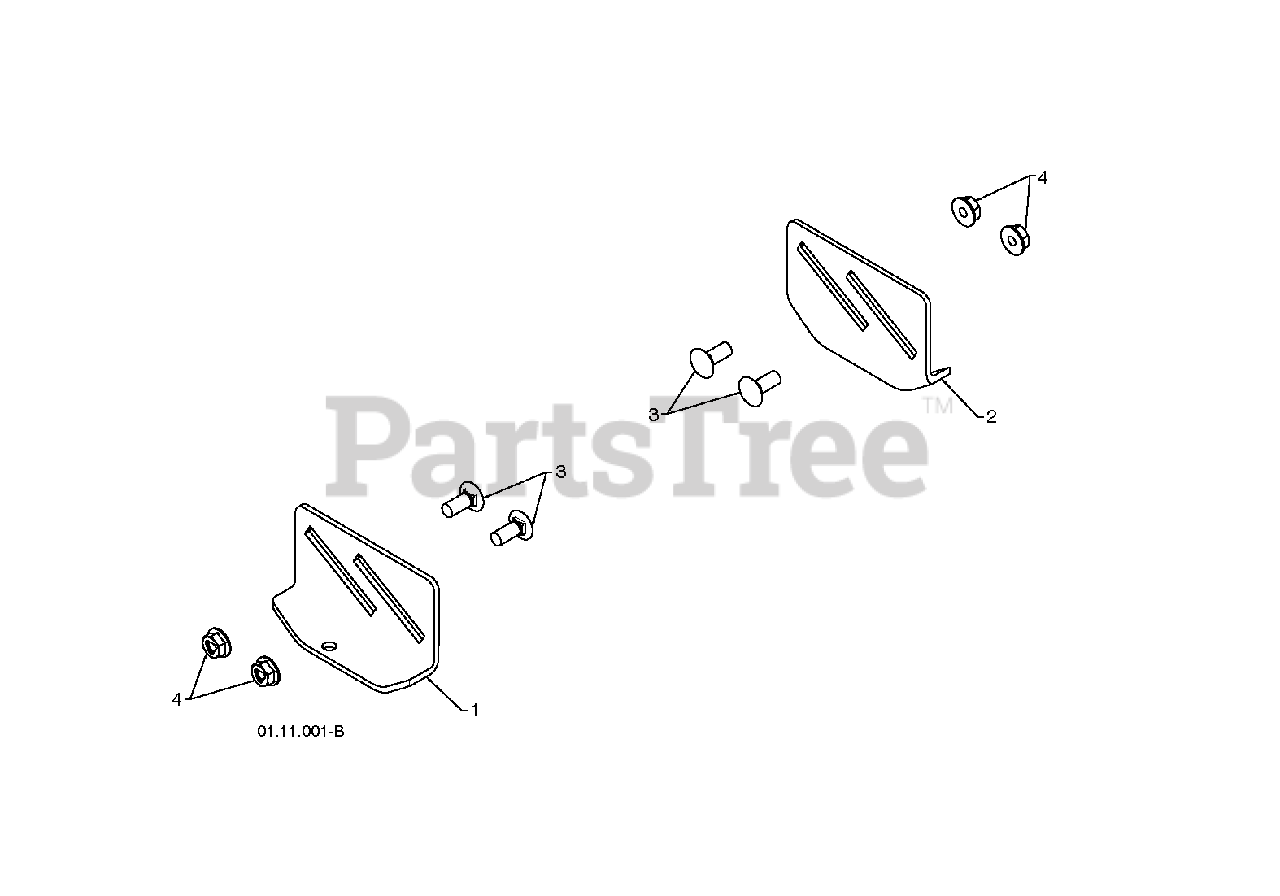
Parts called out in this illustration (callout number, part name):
1	RP PLATE.SKID.LH.PNT
2	PLATE.SKID.ADJ.RH.BLACK
3	BOLT
4	NUT, LOCK 5/16-18
